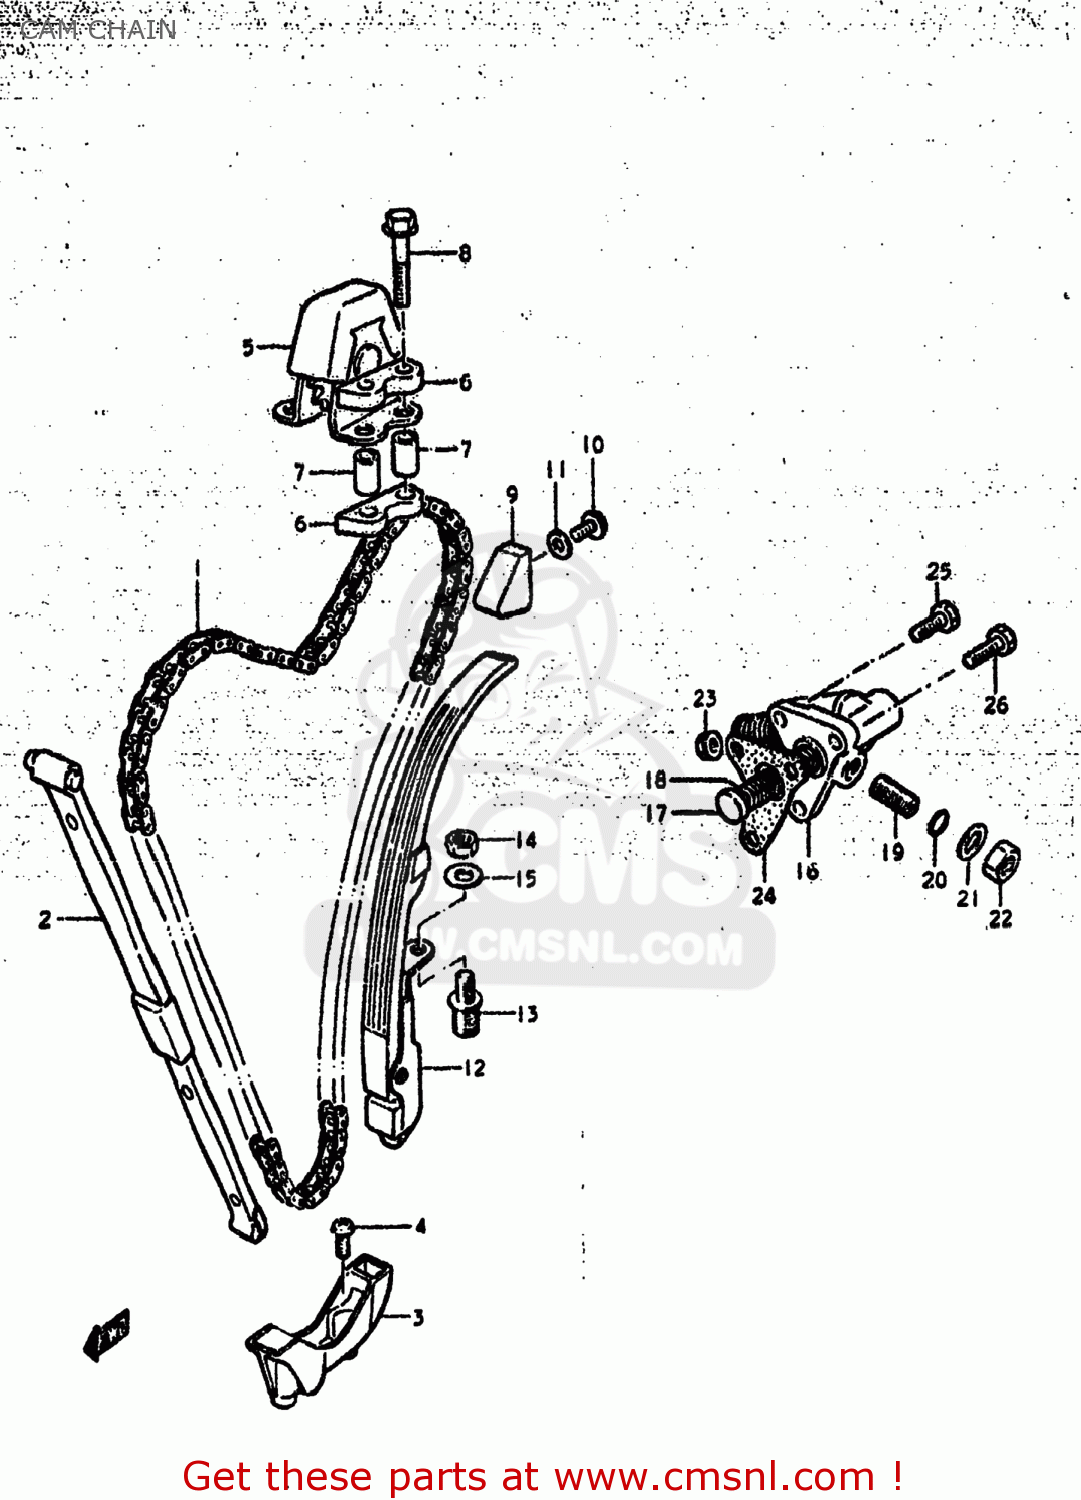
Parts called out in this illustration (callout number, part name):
1	CHAIN,CAMSHAFT DRIVE(120L)
2	GUIDE,CAM CHAIN
3	HOLDER,CAM CHAIN GUIDE
4	SCREW
5	IDLER,CAM CHAIN
6	CUSHION,IDLER
7	SPACER
8	BOLT
9	GUIDE,CAM CHAIN
10	BOLT
11	GASKET (NAS)
12	TENSIONER,CAM CHAIN
13	STUD
14	NUT 8MM
15	WASHER
16	ADJUSTER ASSEMBLY,TENSIONER
17	ROD,PUSH
18	SPRING
19	SCREW
20	O-RING
21	WASHER
22	NUT
23	NUT
24	GASKET,TENSIONER ADJUSTER (MCA)
25	SCREW
26	SCREW
